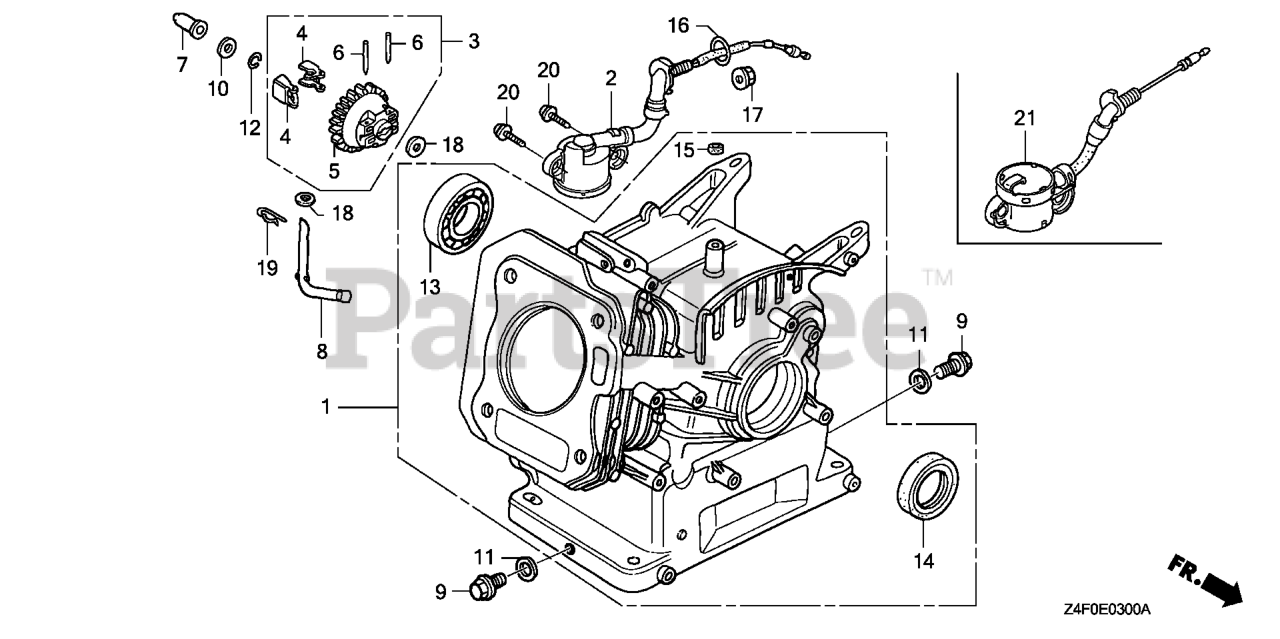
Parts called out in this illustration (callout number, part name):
1	CYLINDER ASSY.
2	SWITCH ASSY., OIL LEVEL
3	GOVERNOR ASSY.
4	WEIGHT, GOVERNOR
5	HOLDER, GOVERNOR WEIGHT
6	PIN, GOVERNOR WEIGHT
7	SLIDER, GOVERNOR
8	SHAFT, GOVERNOR ARM
9	BOLT, DRAIN PLUG
10	WASHER, THRUST (6MM)
11	WASHER, DRAIN PLUG (10.2MM)
12	CLIP, GOVERNOR HOLDER
13	BEARING, RADIAL BALL (62/22)
14	OIL SEAL (22X35X6)
16	O-RING (14MM) (ARAI) Use up to Engine SN 2949254.
17	NUT, FLANGE (10MM)
18	WASHER, PLAIN (6MM)
19	PIN, LOCK (8MM)
20	BOLT, FLANGE (6X12) Use up to Engine SN 1543277.
21	SWITCH ASSY., OIL LEVEL
